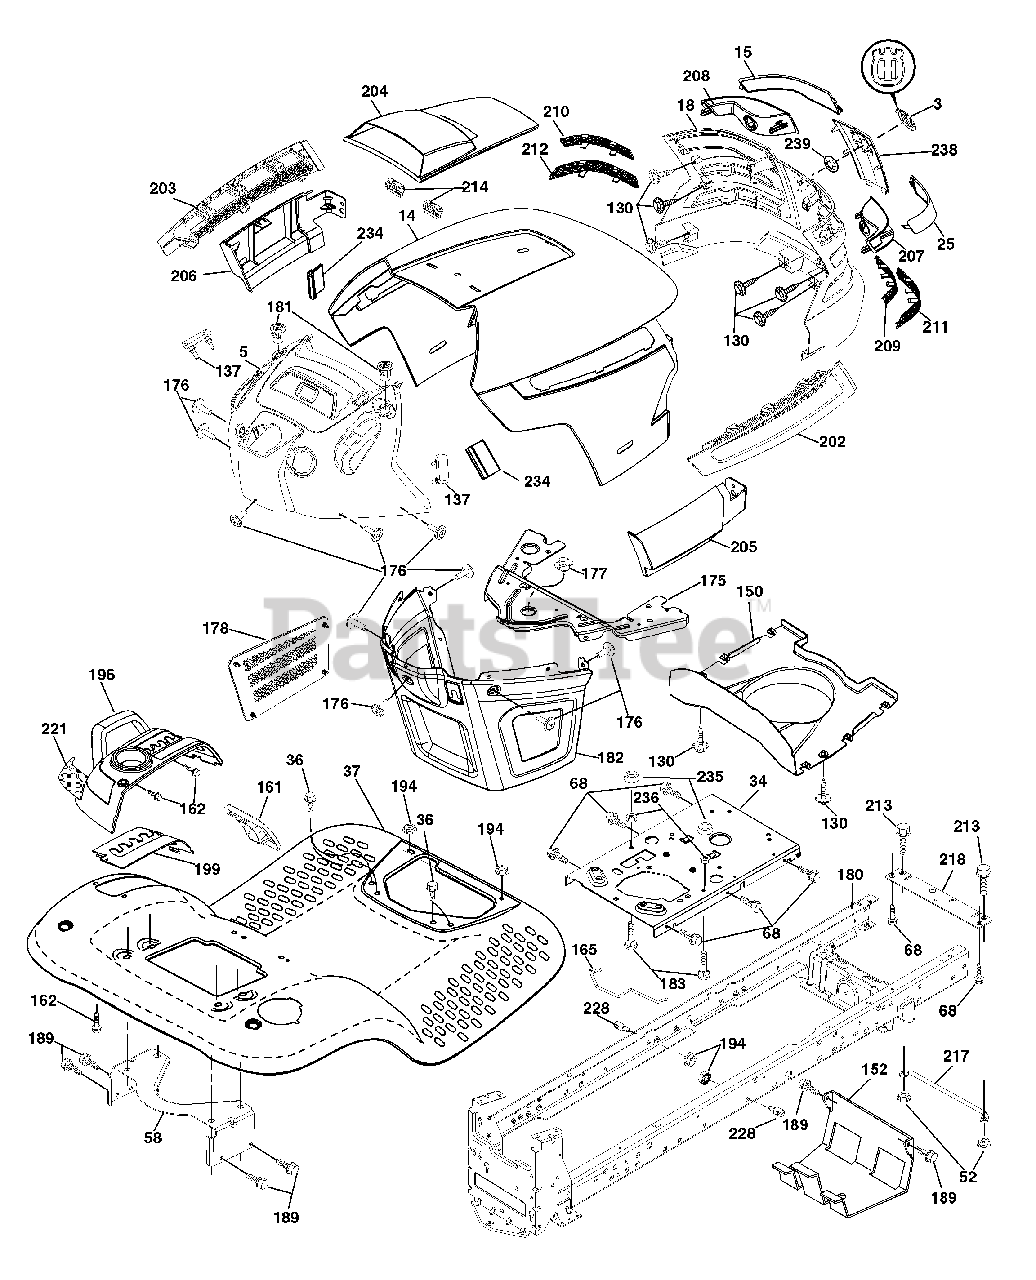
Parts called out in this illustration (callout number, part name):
3	Logo Husq
14	Hood
34	Plate Engine
36	Screw 5/16-18 x 3/4
37	Fender
52	Nut Lock 5/16-18
58	Bracket Fender
68	Screw 5/16-18 x 1/2
130	Screw #10 x 0.750 BOS Thread
137	Bumper Dash
150	Duct Heat Hood
152	Shield Browning/Debris
161	Console Fuel Window
162	Screw Hex Wsh Hi-Lo 1/4 x 1/2
165	Bracket Support Tank
175	Crossmember
176	Screw 10-24 x 5/8 Rnd Qdrx
177	Bushing Steering
178	Cargo Asm. Net
180	Chassis
181	Bushing Mtg. Fender Crgo.
182	Dash Lower
183	Bolt 5/16-18 x 1-1/4
189	Screw 5/16-18 x 3/4
194	Nut Lock Hex Flange 5/16-18
196	Console Asm. Deck Lift
199	Plate Deck Lift
202	Vent Side Hood RH
203	Vent Side Hood LH
204	Vent Asm Hood Top
205	Skirt Hood Side RH
206	Skirt Hood Side LH
209	Insert Hex Top RH
210	Insert Hex Top LH
211	Insert Hex Bottom RH
212	Insert Hex Bottom LH
213	Bolt Hex Hd 5/16-18 unc x 3/4
214	Clip Retainer
221	Reflector LH
228	Stud Fastner
234	Bumper Hood
235	Spacer Fender
236	Nut Lock 5/16-18 unc
239	Plug Mount
